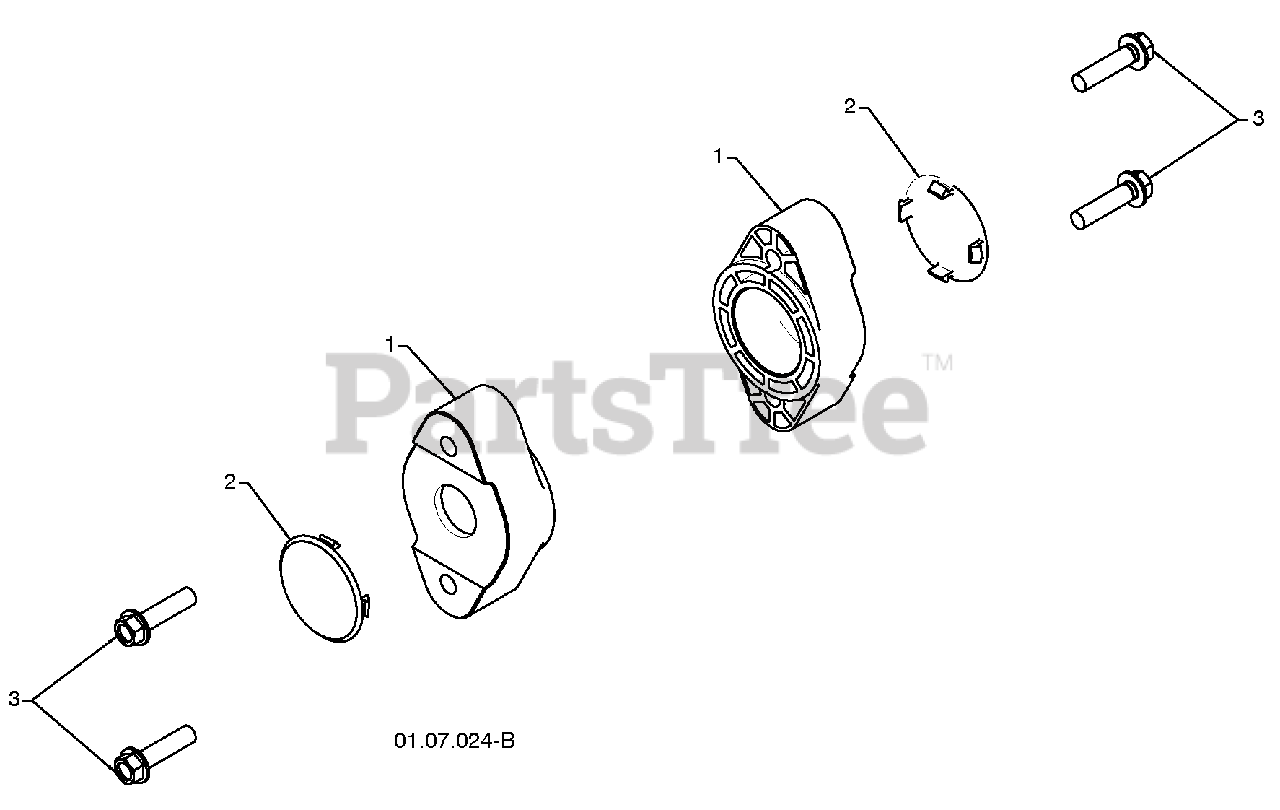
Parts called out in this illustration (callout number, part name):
1	AUGER BEARING
2	BEARING PLUG
3	SCREW 5/16-18 X 1.00
